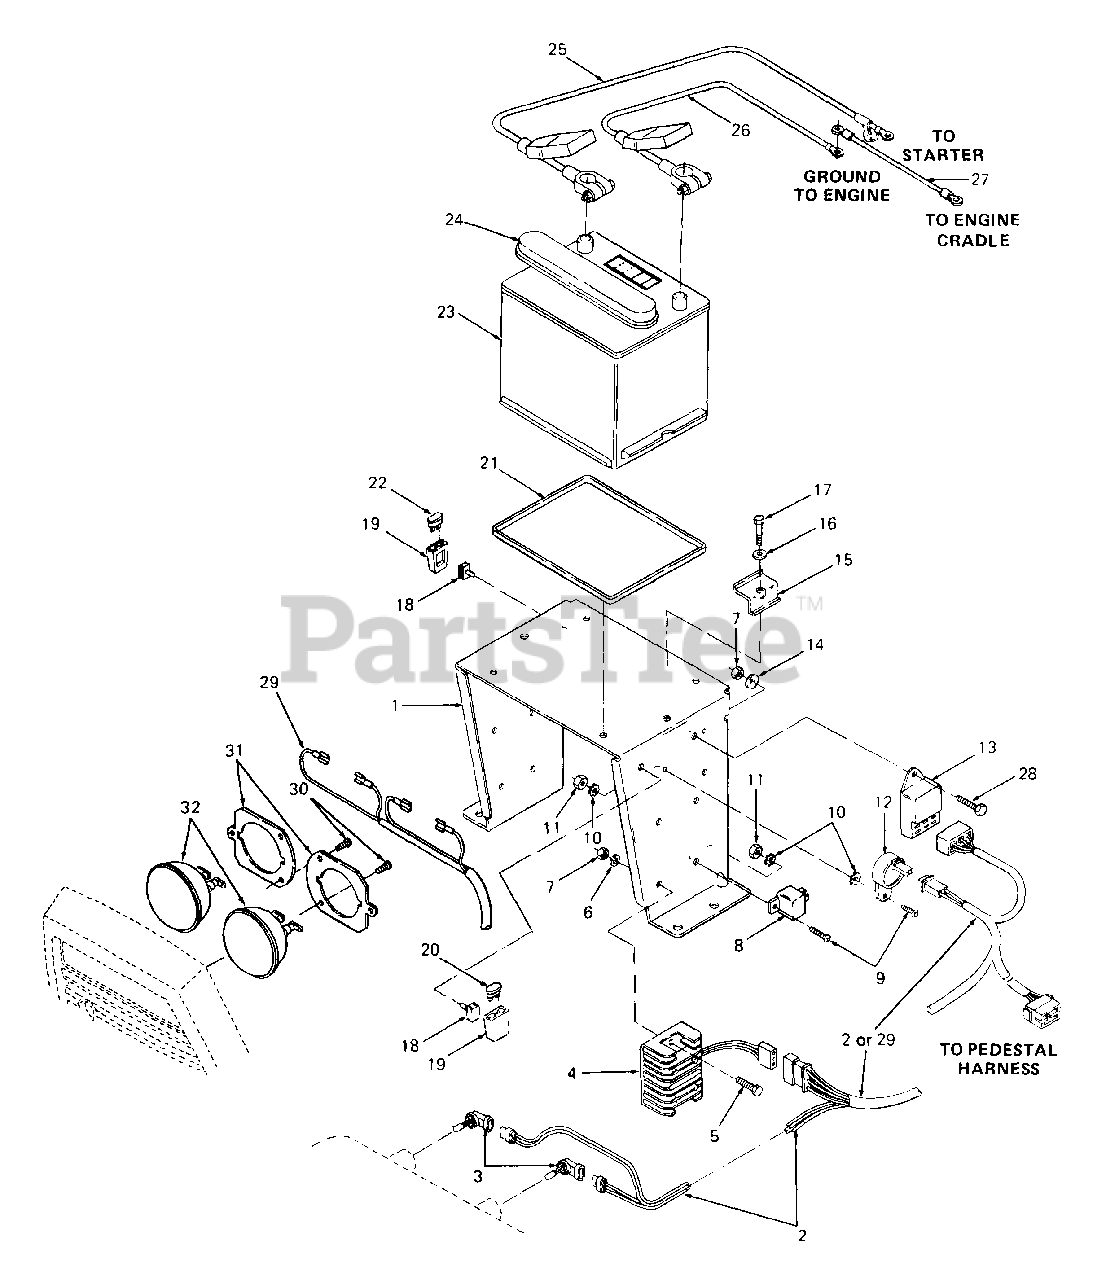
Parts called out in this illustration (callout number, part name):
1	Tray Assy, Battery
2	Harness, Main
3	Bulb, Head Lamp
4	Rectifier
5	Screw, Hex Cap, 1/4-20 X 1.25 Lg
6	Washer, Lock, 1/4
7	Nut, Hex, 1/4-20 GR5
8	Relay
9	Screw, Truss Mach, #10-24 X .50 Lg
10	Washer, External, #10
11	Nut, Hex, #10-24
12	Indicator, Voltage
14	Washer, Bell, .265 X .75 X .062 Thk
17	Screw, Hex Cap, 5/16-18 X 2.0 Lg
18	Clip, Fuse Holder Mtg
19	Holder, Fuse
20	Fuse, 20 Amp (Left side)
21	Tray, Battery
22	Fuse, 30 Amp (Right side)
23	Battery
24	Cap, Battery Vent
25	Cable, Positive Battery
26	Cable, Negative Battery
27	Cable, Ground
28	Screw, Hex Cap, 1/4-20 X .62 Lg GR5
29	Harness, Main Wire
30	Screw, Pan Hd Tapp, #12 x .50 Lg
32	Headlamp, Sealed Beam
